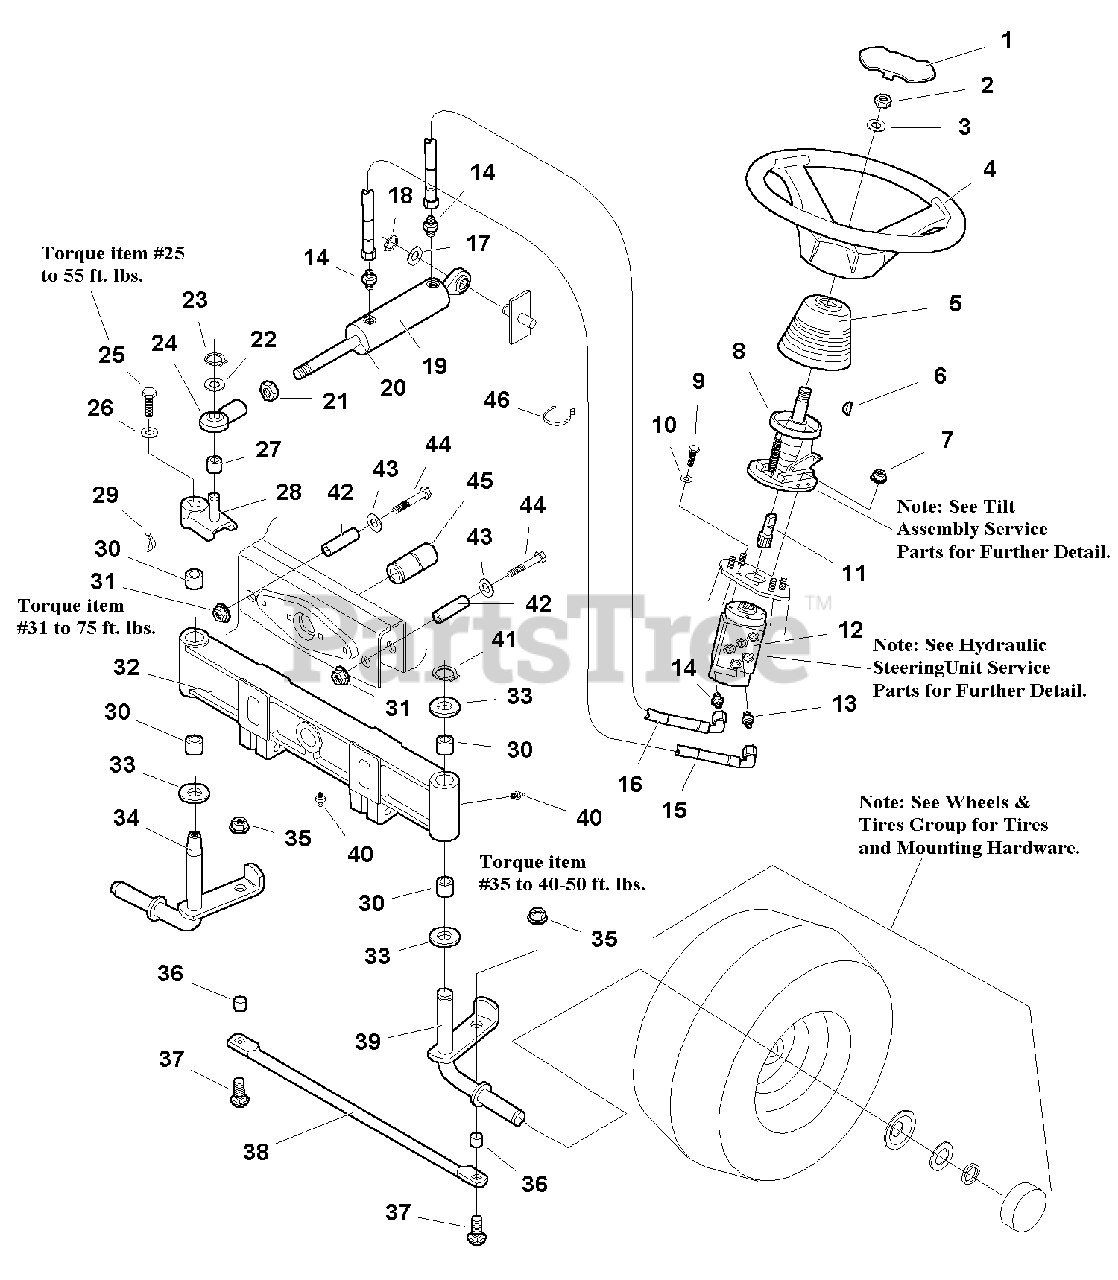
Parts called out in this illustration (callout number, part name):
1	CAP, Steering
2	NUT, Hex, 5/8-18
3	WASHER, 5/8
4	WHEEL ASSEMBLY, Steering
6	KEY, Woodruff, 3/16 x 3/4
7	NUT, Flange Lock, 1/4-20
8	TILT ASSEMBLY (See Tilt Assembly Service Parts )
9	CAPSCREW, M06-1 x 16mm
10	LOCKWASHER, 1/4
11	ADAPTER, Tilt
12	STEERING UNIT, Hydraulic (See Hydraulic Steering Unit Service Parts )
13	FITTING, Hydraulic
14	FITTING, Hydraulic
15	HOSE ASSEMBLY, Steering, 30" Long
16	HOSE ASSEMBLY, Steering, 40" Long
17	WASHER, Plain, 21/32 x 1-1/4
18	RING, Retaining #62
19	CYLINDER, Steering
21	NUT, Hex, Jam, 3/4-16
22	WASHER, Plain, 3/4 x 1
23	RING, Retaining #75
24	BALL JOINT ASSEMBLY
25	CAPSCREW, Hex Head, 3/8-16 x .88
26	WASHER, Spring
27	SPACER, .766 x 1.00 x .62
28	HUB ASSEMBLY, Steering
29	KEY, Hi-Pro
30	BUSHING, Bronze Spindle, .98 x 1.111
31	NUT, Flange Lock, 1/2-13
33	WASHER, 1.00
34	SPINDLE ASSEMBLY, RH
35	NUT, Hex, Flange Lock 7/16-14
36	SPACER, .453 x 3/4 x .39
37	CARRIAGE BOLT, 7/16-14 x 1-1/4
39	SPINDLE ASSEMBLY, LH
40	FITTING, Grease
41	RING, Retainer
42	SPACER, Tube Axle
43	WASHER, 1/2
44	CAPSCREW, Hex Head, 1/2-13 x 3-1/2
45	SPACER, Axle Pivot
